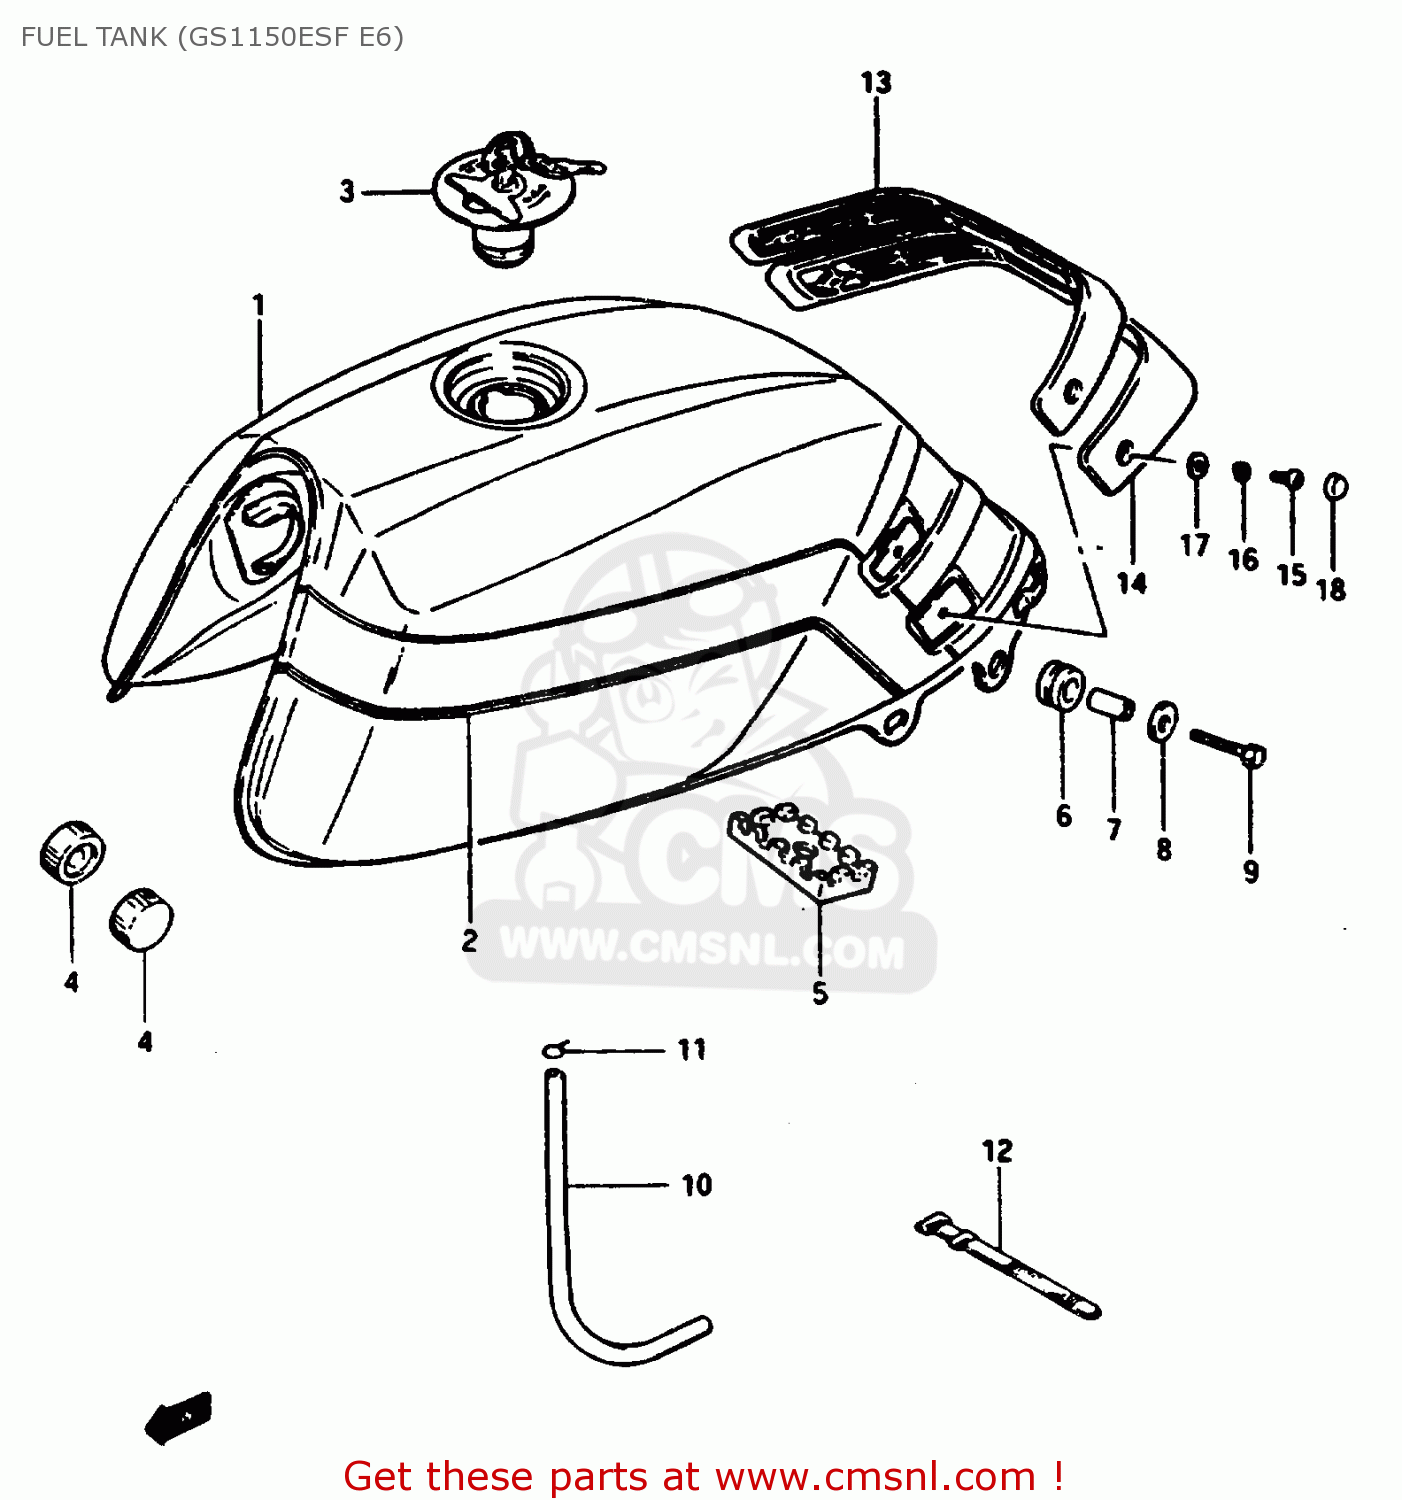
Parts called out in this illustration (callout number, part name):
1	TANK ASSY, FUEL
2	TAPE SET,FUEL TANK
3	CAP ASSY,FUEL TANK
4	CUSHION
5	CUSHION,FUEL TANK CTR
6	CUSHION
7	SPACER (6.4X9X20)
8	WASHER (6.5X29X1.6)
9	BOLT 6X30
10	HOSE,FUEL
11	CLIP
12	CLAMP(L:187)
13	KNEE GRIP,FUEL TANK,UPPER
14	GRIP,FUEL TANK KNEE LWR
15	SCREW
16	LOCK WASHER
17	WASHER
18	CAP,KNEE GRIP
